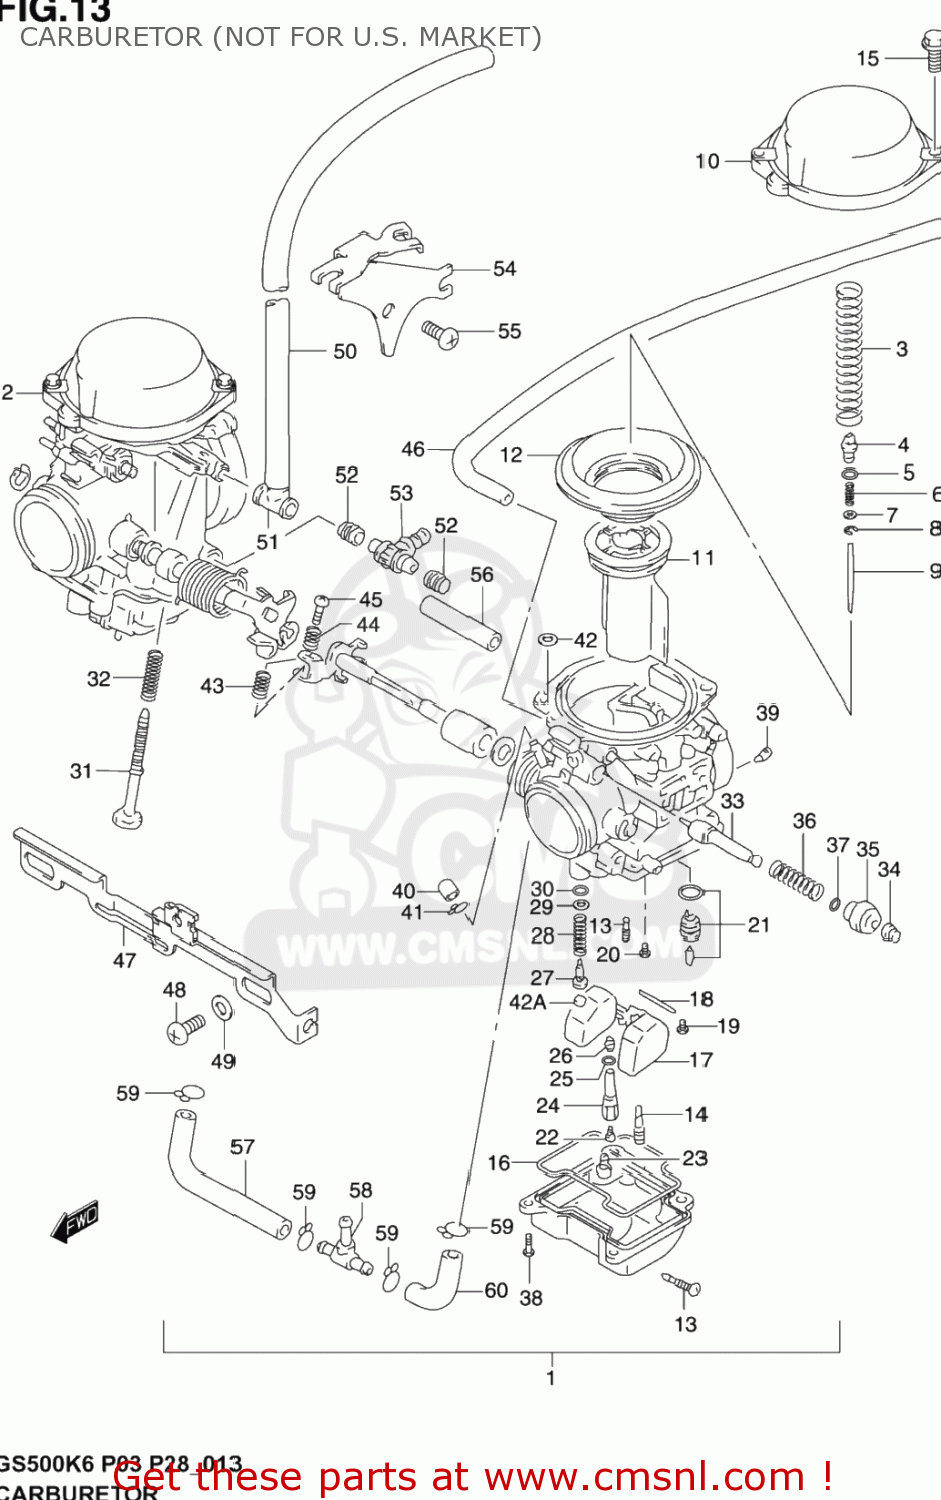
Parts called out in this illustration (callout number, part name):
1	CARBURETOR ASSY,L
2	CARBURETOR ASSY,R
3	SPRING
4	HOLDER
5	O RING(D:1.9,ID:4.8)
6	SPRING
7	WASHER
8	RING
9	NEEDLE,JET(5DH42-1)
10	COVER ASSY,DIAPHRAGM
11	VALVE,PISTON
12	DIAPHRAGM
13	PLUG,DRAIN
14	JET,PILOT(17.5)
15	SCREW
16	GASKET,FLOAT CHAMBER (NAS)
17	FLOAT ASSY
18	PIN,FLOAT
19	SCREW
20	SCREW
21	VALVE ASSY,NEEDLE(NI)
22	JET,MAIN(127.5)
23	JET,MAIN(60)
24	HOLDER,JET
25	O RING
26	JET,NEEDLE(P-5M)
27	ADJUSTER
28	SPRING
29	WASHER
30	O RING,PILOT AIR SCREW
31	SCREW,ADJUST
32	SPRING
33	PLUNGER
34	CAP,STARTER VALVE
35	GUIDE SCREW,PLUNGER
36	SPRING
37	O RING
38	SCREW
39	JET,AIR(160)
40	CAP
41	CLIP
42	O RING
42A	PLUG
43	SPRING,THROTTLE SCREW
44	SPRING
45	SCREW
46	HOSE
47	PLATE
48	SCREW
49	PACKING
50	HOSE
51	HOSE
52	SEAL
53	NIPPLE
54	BRACKET
55	SCREW
56	PIPE
57	HOSE
58	NIPPLE
59	CLIP
60	HOSE
